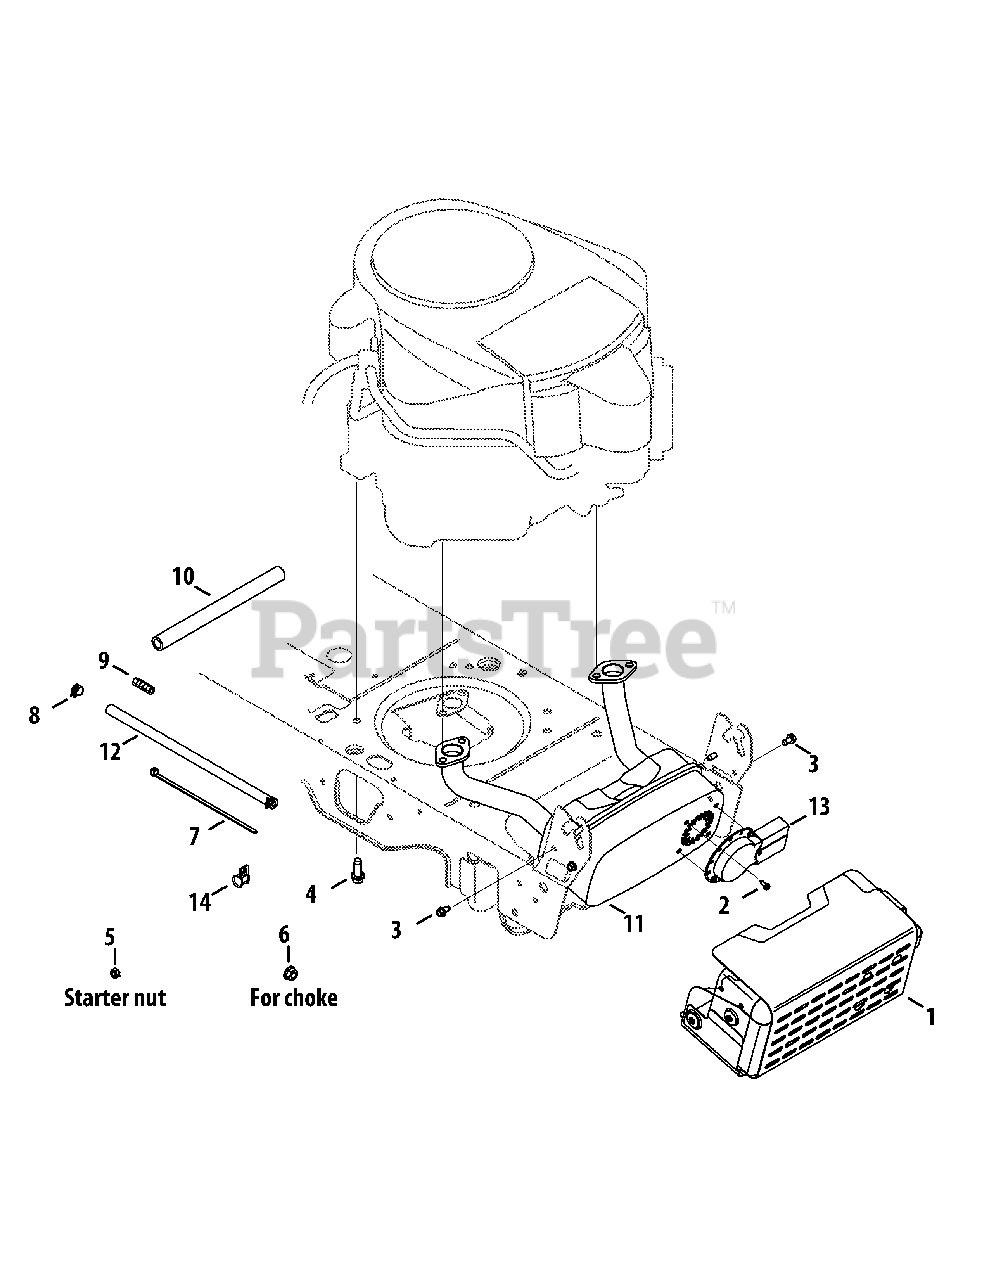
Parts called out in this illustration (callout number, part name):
1	Shield Ass’y, Muffler
2	Screw, Ab, #8-18, 0.500,
3	Screw, Self-tapping, 1/4-20, 0.500,
4	Screw, Self-tapping, 3/8-16, 1.25
5	Nut, Sems, 1/4-20
6	Nut, Flange Lock, 3/8-16 Kaw.
7	Cable, Tie, 3/16 x .05 x 7.4
8	Clamp, Hose, .490 Dia.
10	Hose, Extension, Oil Drain
11	Muffler, Kawasaki Twin
12	Hose, Fuel, Low Permeation, 1/4
13	Deflector, Muffler, Long
14	Clamp, 1.0 Dia.
